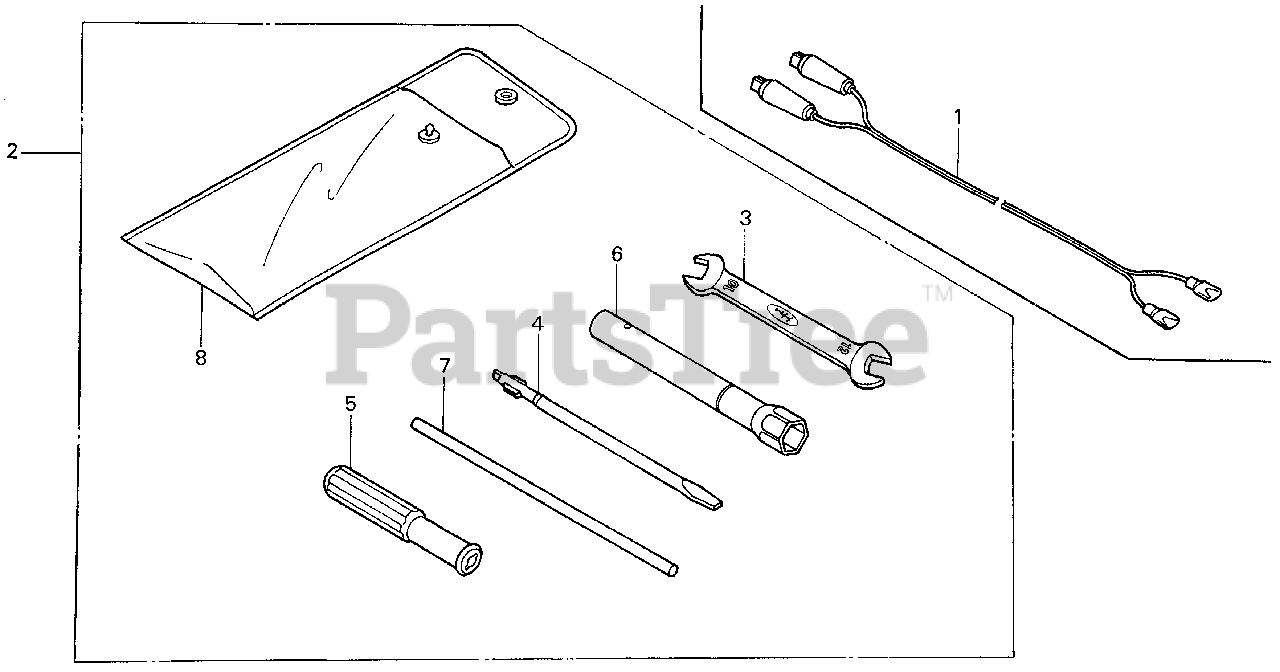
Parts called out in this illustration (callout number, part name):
1	WIRE ASSY., CHARGE
2	TOOL KIT (N/A: SEE COMPONENTS)
3	WRENCH (10X12) (OPEN END)
4	SCREWDRIVER 3, STRAIGHT SLOT (NO.2)
6	WRENCH, BOX (P21)
7	BAR A, HANDLE
